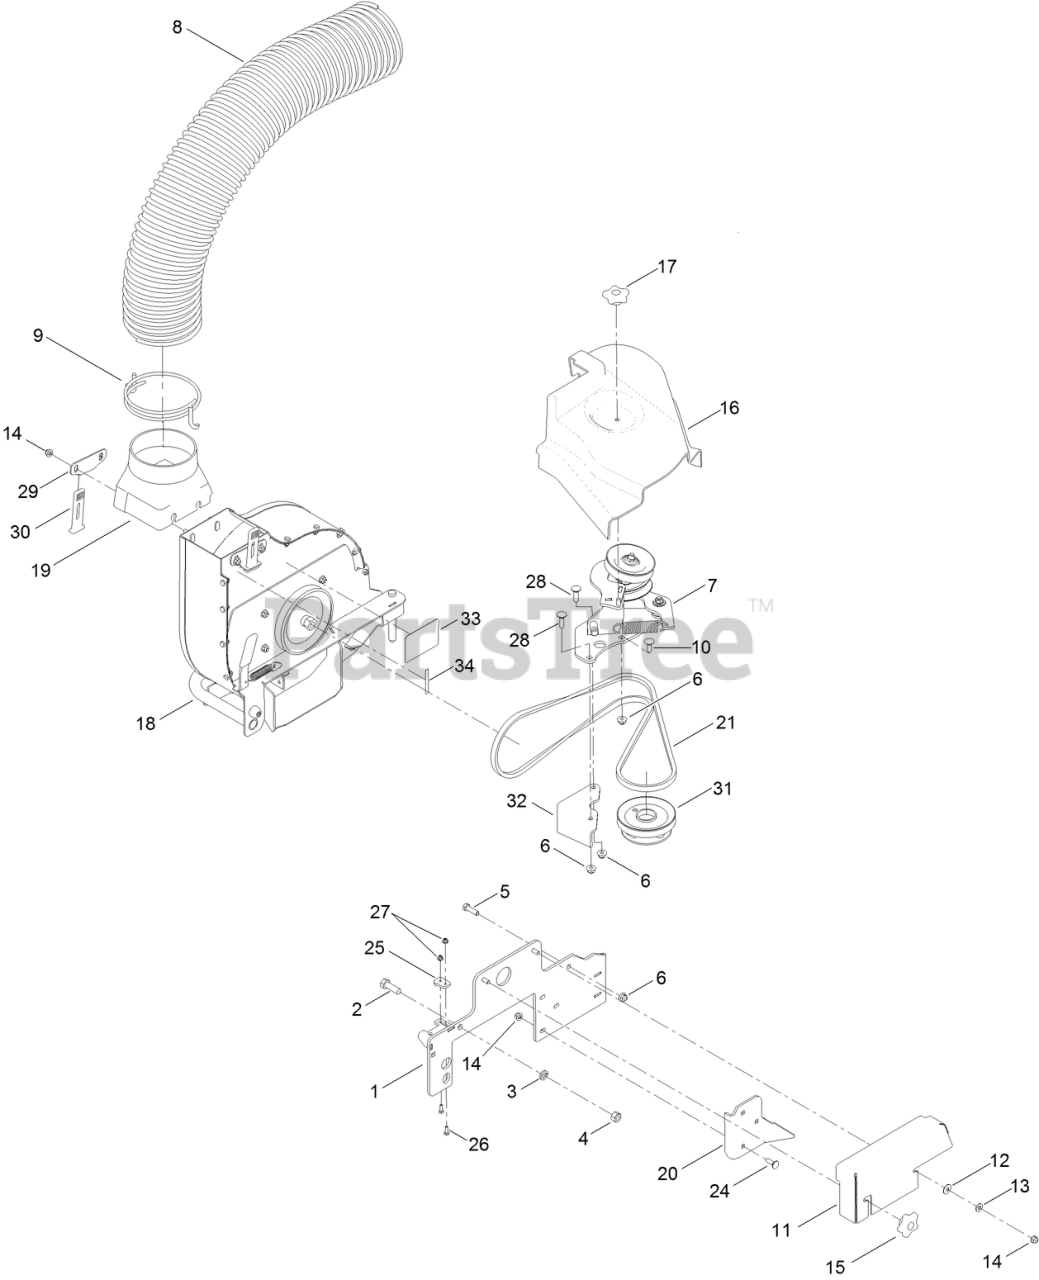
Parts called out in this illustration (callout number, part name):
1	BLOWER DECK MOUNT ASM
2	SCREW-HH
3	WASHER-LOCK
4	NUT-HH
5	SCREW-HH
6	NUT-HF, NI
7	IDLER ASM
8	HOSE-FLEXIBLE
9	CLAMP-HOSE, BAGGER
10	BOLT-CARR
11	GUARD-BELT, BLOWER
12	WASHER-BELLEVILLE
13	WASHER-RUBBER
14	NUT-HF, NI
15	KNOB-HANDLE
16	COVER-BELT
17	KNOB-HANDLE
18	BLOWER ASM
19	TRANSITION-BLOWER
21	BELT-V
24	BOLT-CARR
25	PLATE-LATCH
26	SCREW-CARR
27	NUT-HF
28	BOLT-CARR
30	STRAP-HOLD DOWN
31	BLOWER PULLEY ASM
32	BAFFLE-BAGGER
33	DECAL-ROUTING, BELT
34	DECAL-WARNING
